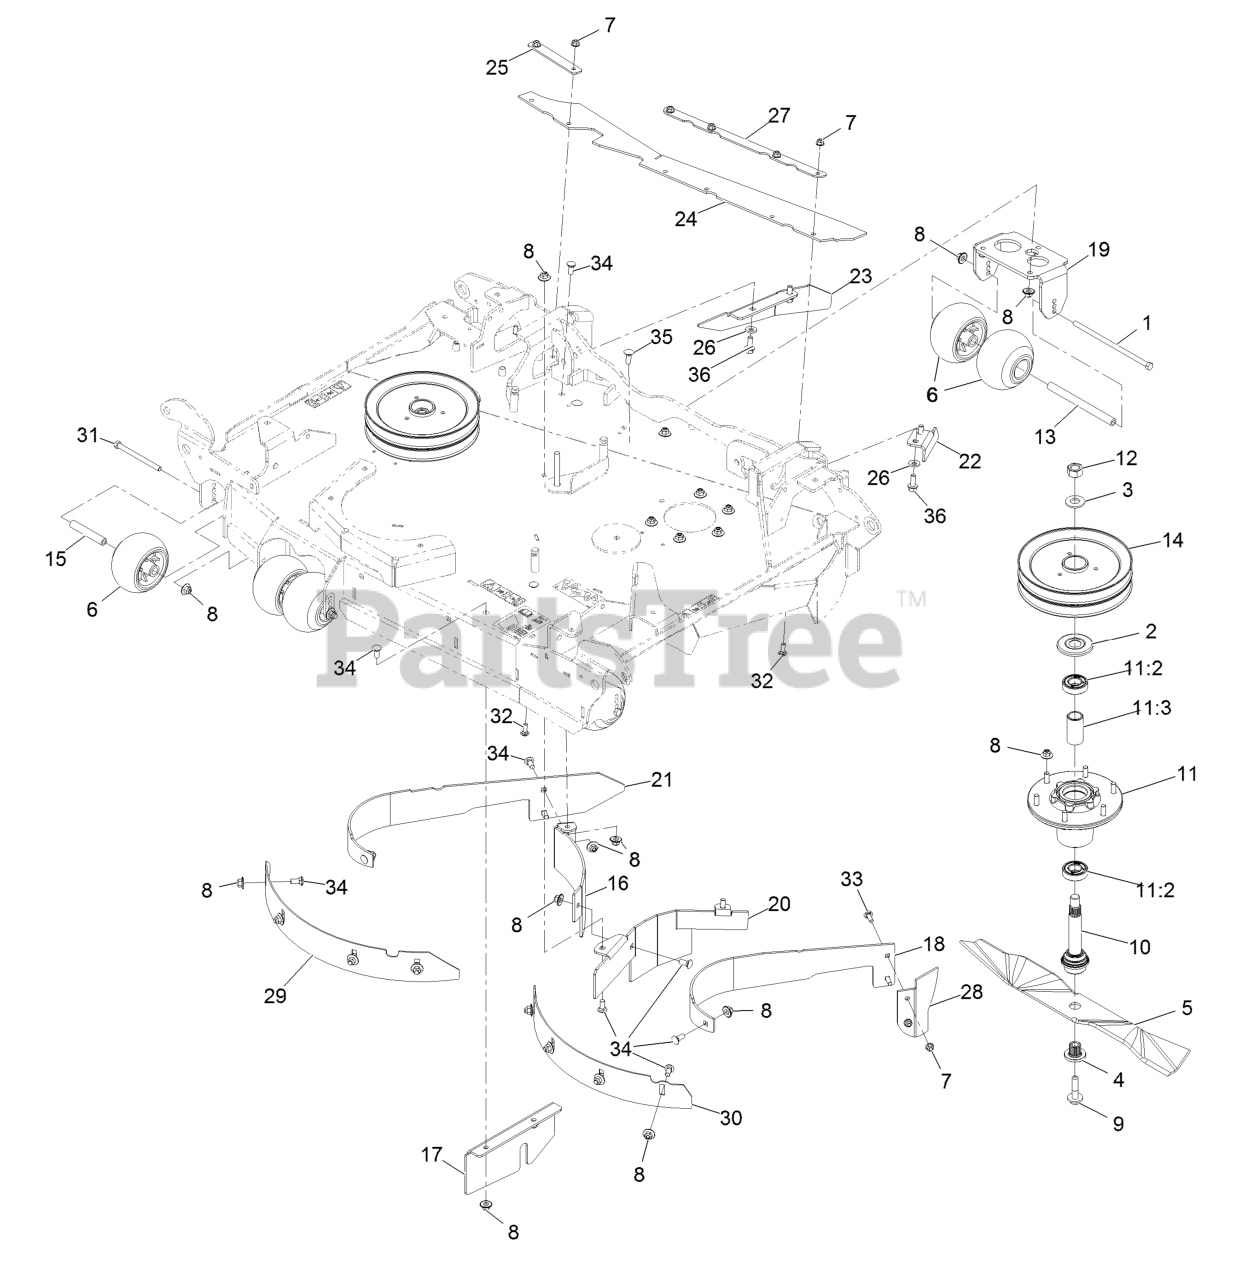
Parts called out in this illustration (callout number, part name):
1	Screw-HH
2	Guard-Bearing Top
3	Washer-Spring Disc 3/4
4	Bushing, Splined
5	Blade, Mulching
6	Roller-Anti-Scalp
7	Nut-Nyloc 5/16-18 Flg
8	Nut-Nyloc 3/8-16 Flg
9	Screw-Sems 1/2-20 X 2.19
10	ASM-Spindle And Seal
11	ASM-Cutter Hsg With Bearings
11:2	Bearing-Ball
11:3	Spacer-Bearing
12	Nut-Hex
13	Spacer-Wheel
14	Sheave-Double 96Rd
15	Spacer-Wheel Short
16	Baffle-Center, Rear (RH)
17	Plate-Block, Front
18	Baffle-Dogleg, Center (LH)
19	Bracket-Antiscalp, Rear
20	Baffle-Center
21	Baffle-Dogleg, Center (RH)
22	Baffle-Breaker
23	Plate-Fin, Discharge
24	Flap-Discharge
25	Support-Flap, LH
26	Washer-Belleville
27	Support-Flap, LH
28	Guard-Discharge
29	Baffle-Depth, LH
30	Baffle-Depth, RH
31	Screw-HH 3/8-16 X 4 3/4
32	Bolt-Carriage 5/16-18 X 7/8
33	Bolt-Carriage 5/16-18 X 1 Sp
34	Bolt-CARR
35	Bolt-Carriage 3/8-16 X 1
36	Screw-HH Flg 3/8-16 X 1
